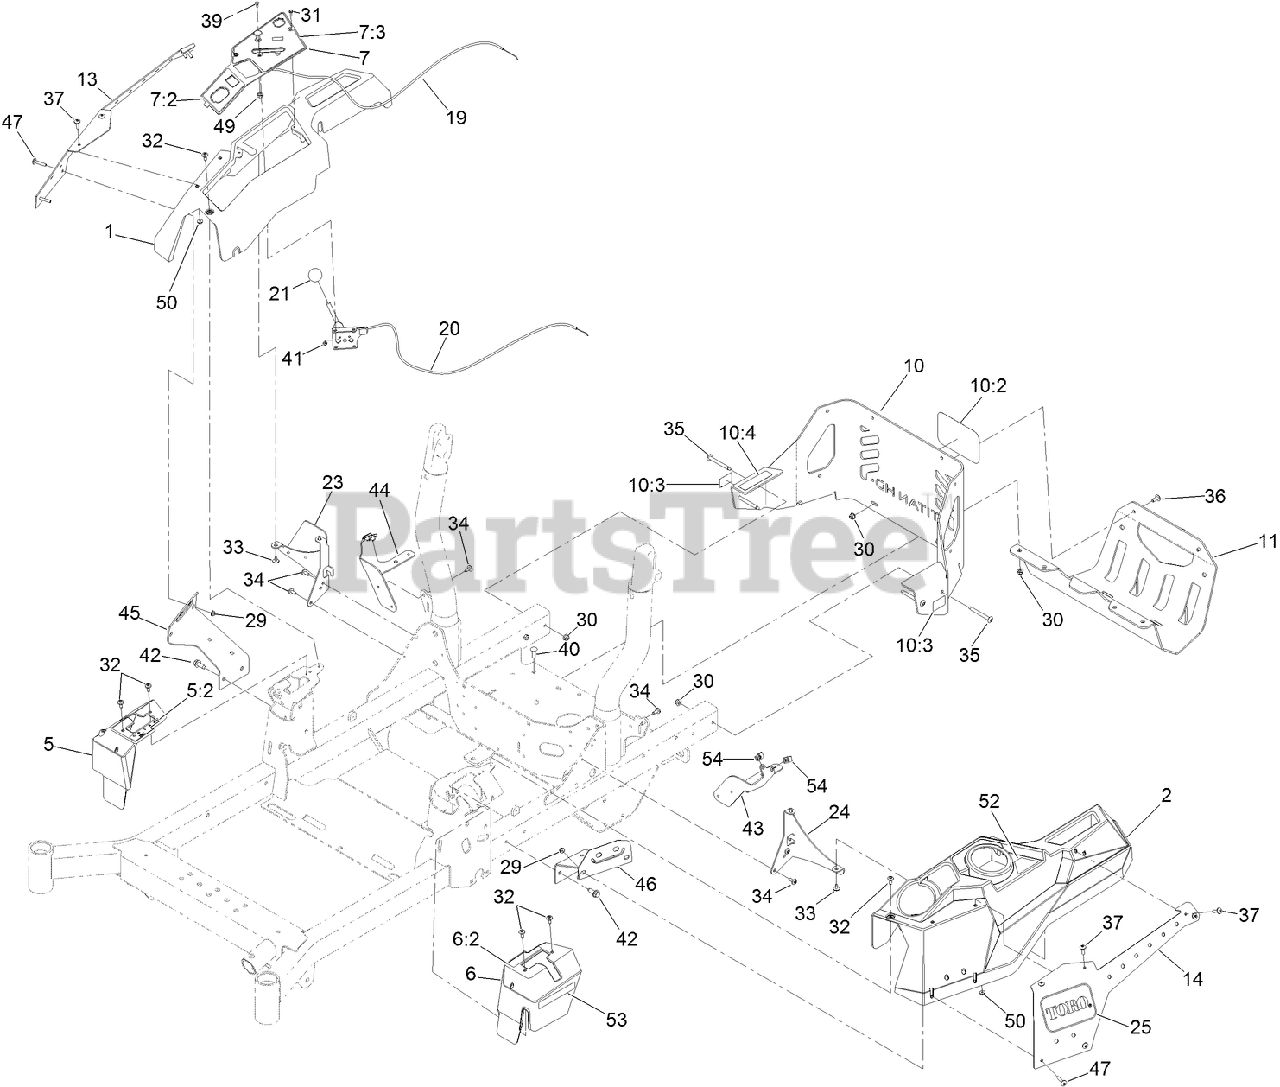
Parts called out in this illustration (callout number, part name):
1	CONSOLE-RH
2	CONSOLE-LH
5	COVER-CONTROL, MOTION (RH)
5:2	DECAL-CONTROL, MOTION (RH)
6	COVER-CONTROL, MOTION (LH)
6:2	DECAL-CONTROL, MOTION (LH)
7	CONTROL PANEL ASM
7:2	DECAL-PANEL, CONTROL
7:3	DECAL-PANEL, CONTROL
10	REAR GUARD ASM
10:2	DECAL
10:3	DECAL-WARNING
10:4	DECAL-ARRESTER, SPARK
11	GUARD-MUFFLER
13	COVER-POD, RH
14	COVER-LH
19	CABLE-CONTROL, CHOKE
20	CABLE-CONTROL, THROTTLE
21	KNOB-BALL
23	SUPPORT-CONSOLE, RH
24	BRACKET-CONSOLE, LH
25	DECAL
29	NUT-HF
30	NUT-HF, NI
31	SCREW-HWH
32	SCREW-SHOULDER
33	SCREW-TORX
34	SCREW-TORX
35	SCREW-TORX
36	SCREW-TORX
37	SCREW-TRUSS
39	BOLT-CARR
40	SCREW-CARR
41	NUT-LOCK, NI
42	SCREW-FORMING, THREAD
43	BRACKET-SUPPORT, LEFT POD
44	BRACKET-SUPPORT, RIGHT POD
45	BRACKET-SUPPORT, POD (RH)
46	BRACKET-SUPPORT, POD (LH)
47	SCREW-TRUSS
49	NUT-HJ
50	NUT-KEPS
52	DECAL-FILL, FUEL
54	NUT-RETAINER
